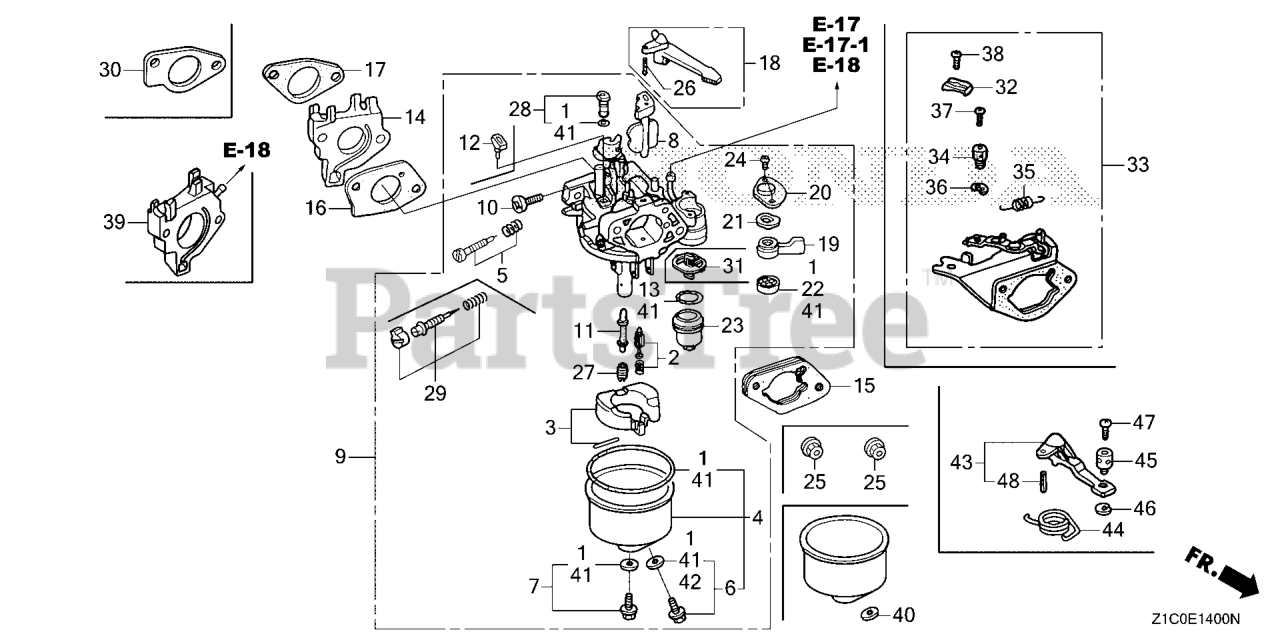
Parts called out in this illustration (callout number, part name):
2	VALVE SET, FLOAT
3	FLOAT SET (CARBURETOR NO.)
4	CHAMBER SET, FLOAT
6	SCREW SET, DRAIN
7	SCREW SET (CARBURETOR NO.)
9	CARBURETOR ASSY. (BE94J A)
10	SCREW, THROTTLE STOP
11	NOZZLE, MAIN
12	COLLAR, SET
13	GASKET, FUEL STRAINER CUP
14	INSULATOR, CARBURETOR
15	SPACER, CARBURETOR
16	GASKET, CARBURETOR
19	LEVER, VALVE
20	PLATE, LEVER SETTING (CARBURETOR NO.)
21	SPRING, PETCOCK LEVER (CARBURETOR NO.)
22	GASKET, VALVE
23	CUP, FUEL STRAINER
24	SCREW, PAN (3X6)
27	JET, MAIN (#110) (CARBURETOR NO.)
27	JET, MAIN (#112)
27	JET, MAIN (#118)
28	JET SET, PILOT (#45)
29	SCREW SET (Honda Code 4219879). (CARBURETOR NO.)
30	GASKET, CARBURETOR INSULATOR
31	FILTER, CUP (CARBURETOR NO.)
41	GASKET SET (INCLUDE 16173-001-004) (INCLUDES 16173-001-004)
42	WASHER, PLAIN (6.2X10.7 DRAIN) (CARBURETOR NO.)
43	LEVER, CHOKE (REMOTE)
45	HOLDER, CABLE
46	CIRCLIP (5MM) Use from Engine SN 2327377.
47	SCREW, PAN (4X8)
48	PIN, SPRING (2X12)
